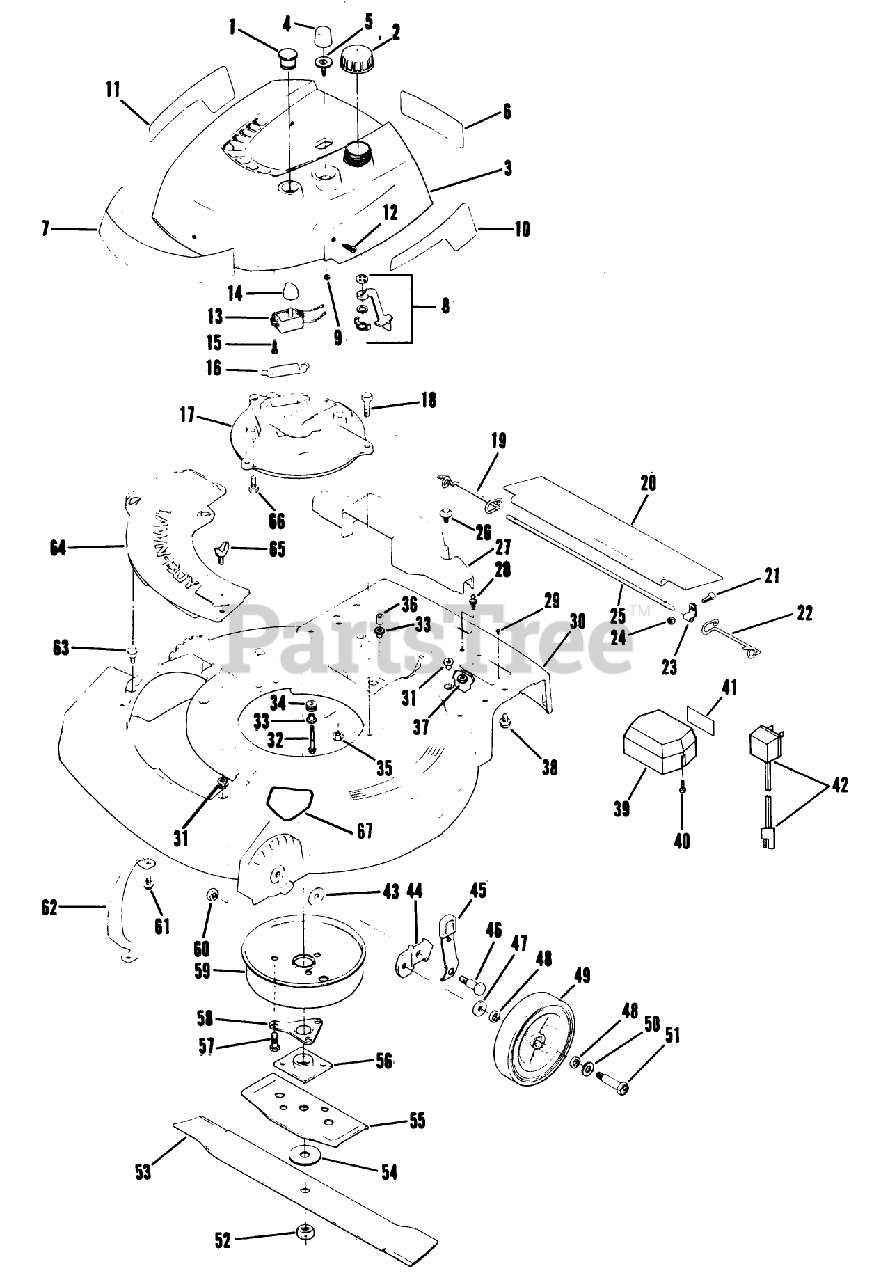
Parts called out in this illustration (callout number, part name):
1	F-PLUG
9	LOCKNUT S
12	SCREW S
14	SWITCH KNOB
18	SCREW
19	SPRING;TRAILING SHIELD RH
20	SHIELD
22	SPRIG T/SHLD ASOC
23	CLAMP ROD KMC
24	LOCKNUT E
25	ROD 21" ADVANCE
26	SCREW SEMS TRM HEX HD
32	Screw-Sems
33	SPACER ECK PRES
34	GROMMET
35	NUT-LOCK F
36	SPACER
38	SCREW
43	WASHER
47	WASHER WROUGHT
48	WASHER
49	WHEEL & TIRE KIT
50	SPACER
51	BOLT WHEEL
52	NUT-BLADE
54	WASHER
56	PLATE AND COLLAR ASM
57	SCREW
58	SUPPORT F
60	LOCKNUT
62	BAR-TOE
64	COVER PLATE
65	WING SCREW LAWRE
66	SCREW V
